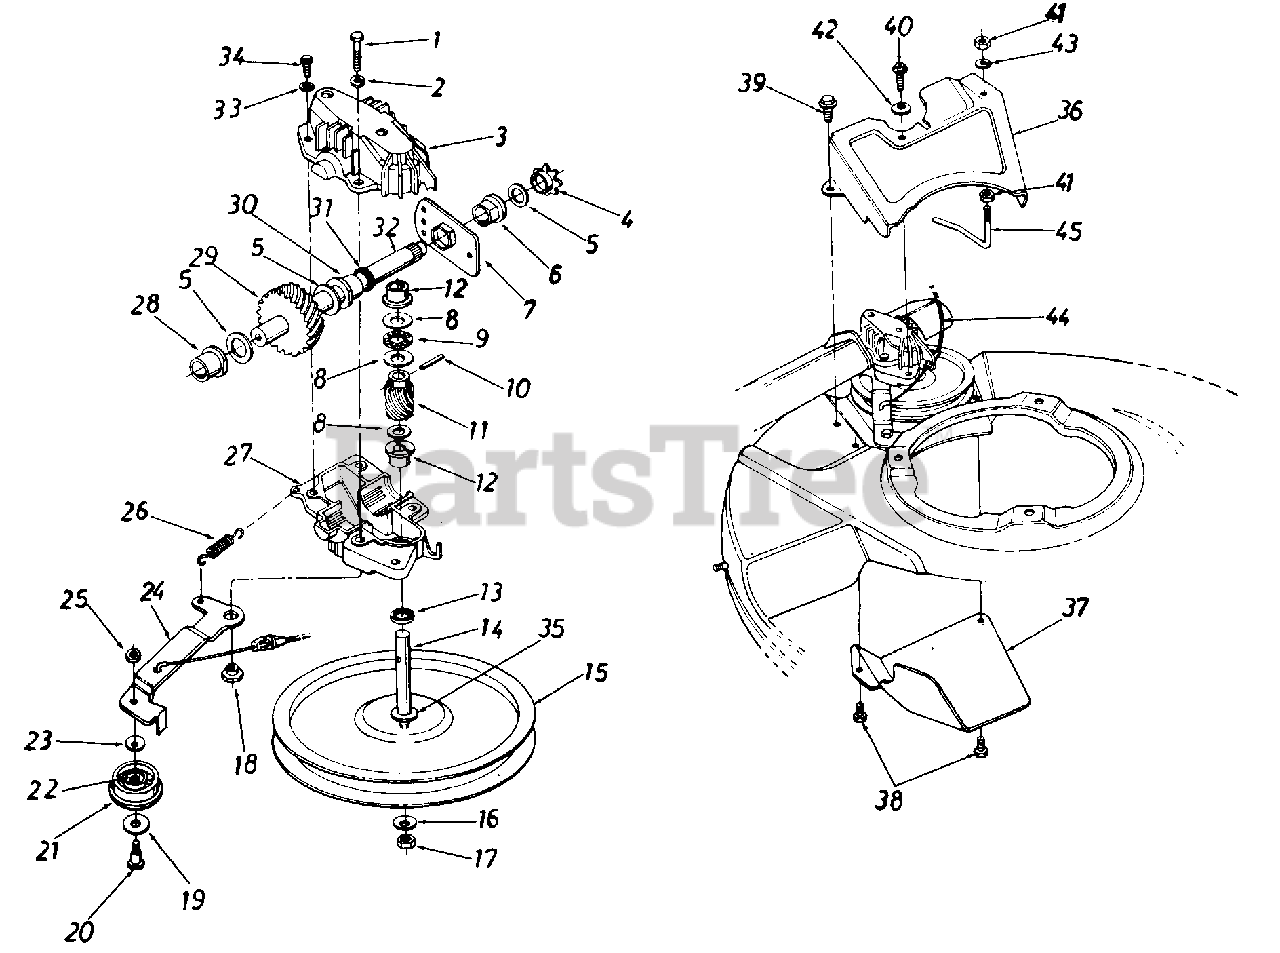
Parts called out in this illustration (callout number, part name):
1	Hex Bolt 1/4-20 x 1.25" Lg.
2	L-Wash. 1/4" I.D.
3	Upper Hsg. Half
4	#48 Sprocket 7 Tooth x 1/2 Pitch
5	Fl-Wash. 5/8" I.D. x .030
6	Hex Flange Brg. .631" I.D.
7	Hex Bearing Cup
8	Thrust Wash. .382" I.D. x .70" O.D.
9	Thrust Bearing .375" I.D. x .812" O.D.
10	Spring Pin Spir. 1/8" x .62" Heavy
11	11 Tooth Helical Gear
12	Flange Bearing
13	Oil Seal
14	Pulley-Transmission Shaft
15	Fl-Pulley 5.06" I.D.
16	Bell-Wash. .265" I.D. x .75"
17	Hex Nut 1/4-28 L.H. Thd.
18	Shld. Spacer .375" Dia. x .170
19	Fl-Wash. .390" I.D. x 1.0"
20	Shld. Bolt .375" Dia. x .40"
21	Fl-Idler Plastic 1.50" Dia
22	Needle Brg. .375" x .31"
23	Bell-Wash. .265" I.D. x 75"
24	Idler Brk't. Ass'y.
25	Hex Patch L-Nut 1/4-28 Thd.
26	Extension Spring 1.12" Lg.
27	Lower Hsg. Half
28	Flange Bearing .566 Dia.
29	33 Tooth Helical Gear
30	Flange Bearing .629 Dia.
31	Oil Seal .625 Dia.
32	Gear Sprocket Shaft
33	L-Wash. #10 I.D.
34	Hex B-Tap Scr. #10 x .62"
35	Hex Washer .26" x .88"
36	Transmission Belt Guard
39	Hex AB-Tap Scr. 1/4 x .50" Lg.
40	Hex B-Tap Scr. 1/4 x .62" Lg.
41	Hex Nut 1/4-20 Thd.
42	Bell-Wash. .265" I.D. x .75"
43	L-Wash. 1/4" I.D.
44	S.P. Cable-50" Lg.
45	S.P. Belt Guard
